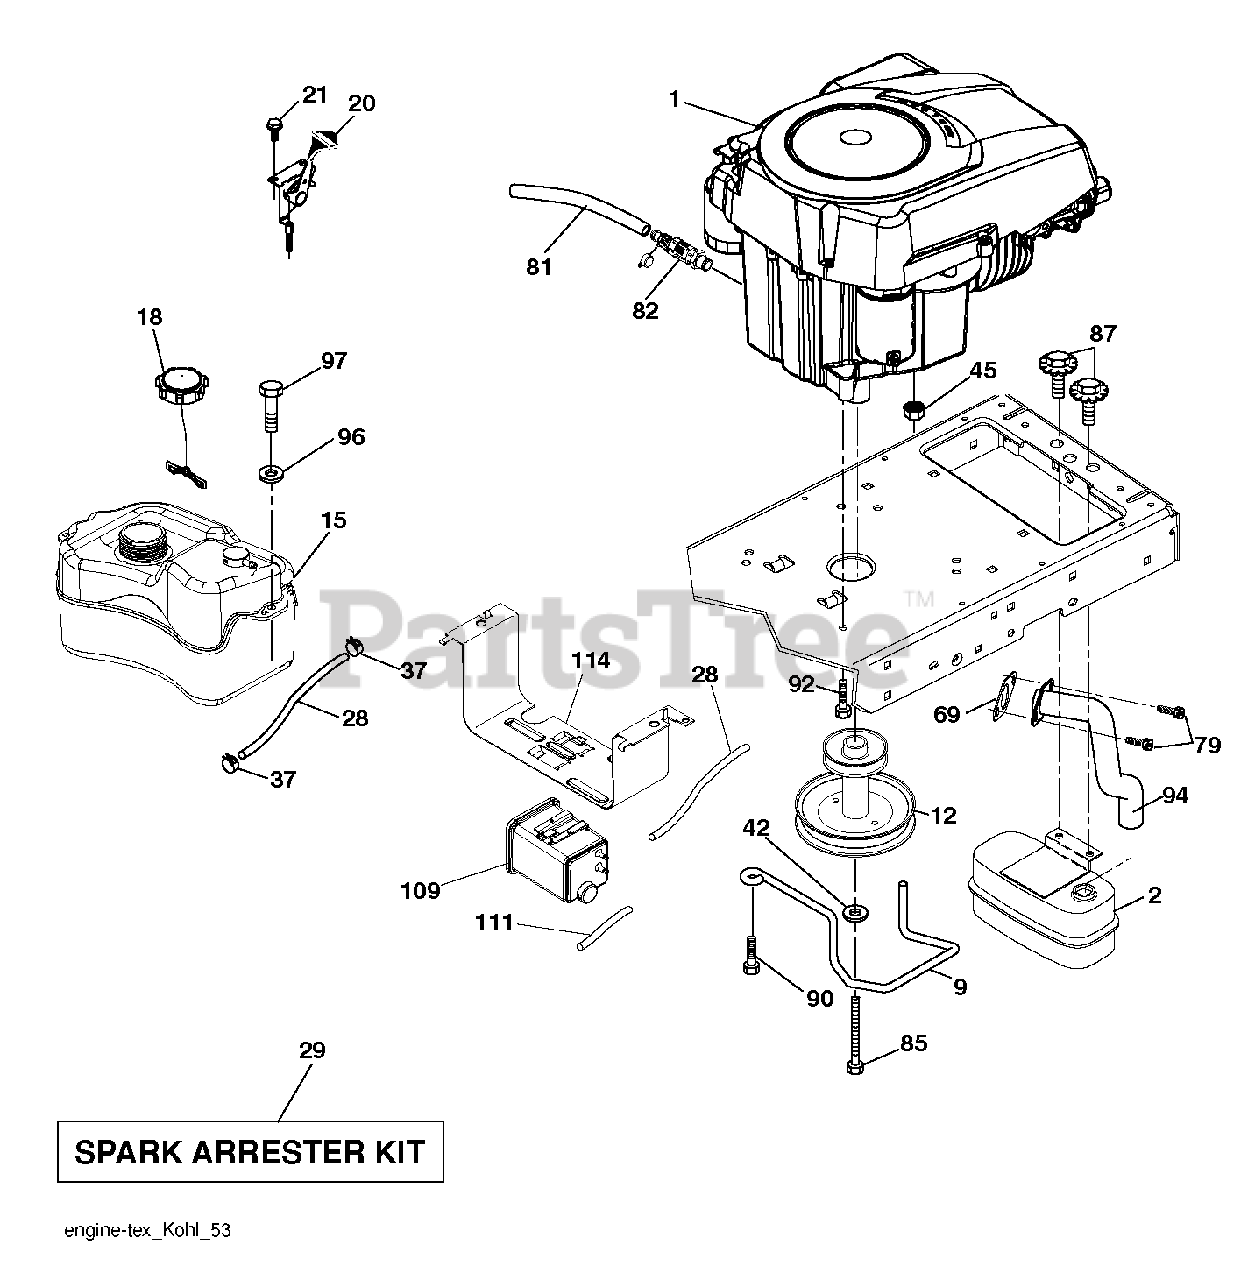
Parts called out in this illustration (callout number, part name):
9	KEEPER.BELT.ENGINE.4.2
21	SCREW.#10 X 0.750.BOS THREAD
29	ARRESTER SPARK (OPTIONAL)
37	HOSE CLAMP
42	LOCKWASHER
79	SCREW.SOCKET HD.5/16-1
81	TUBE, DRAIN OIL ASM.
82	VALUE.OIL.DRAIN
87	BOLT, 5/16-18 X 1 3/4
90	SCREW 3/8-16X1
92	SCREW 3/8-16X1
97	SCREW HEXWSHR 1/4-20X3/4
109	CANNISTER, CARBON
